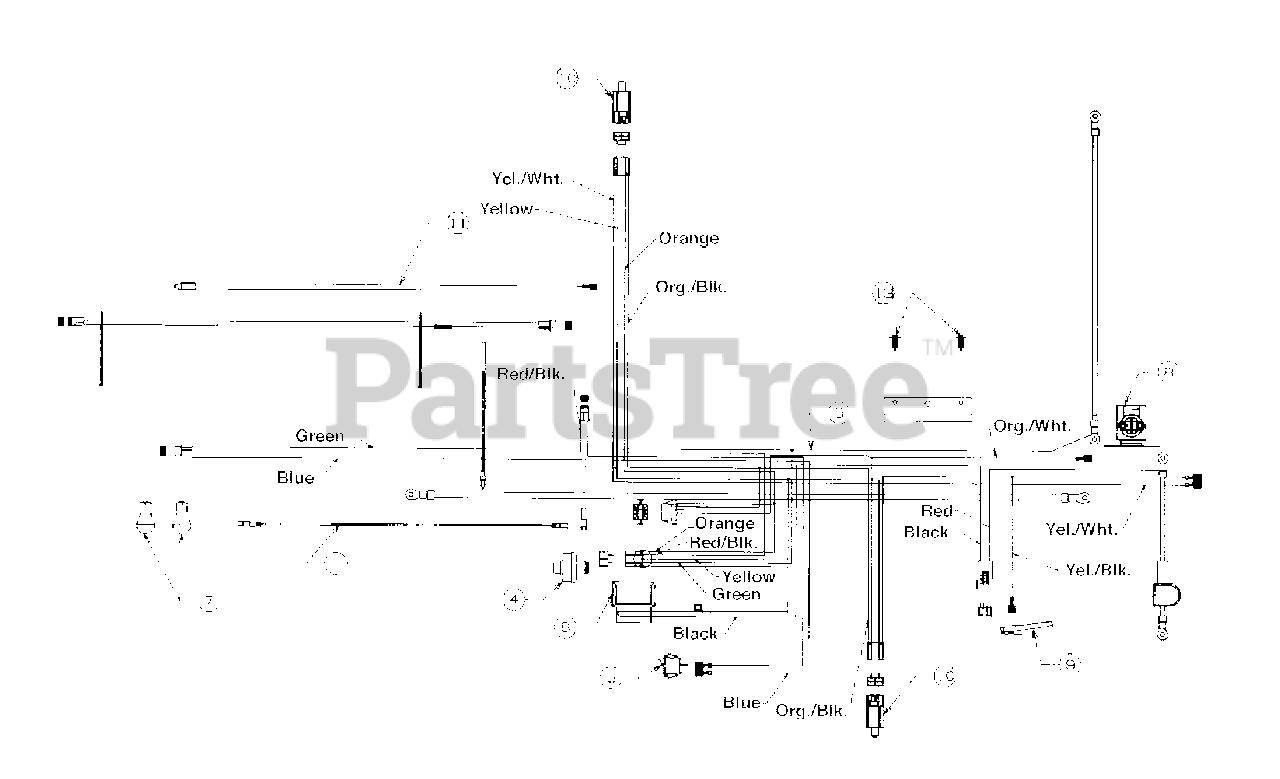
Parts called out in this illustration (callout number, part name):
2	Harness Adapter
3	Wire Harness w/Light Switch & Amp
4	Ignition Switch
5	Light Switch
6	Ammeter
7	Bulb
8	Solenoid
9	Safety Switch
10	Safety Switch
11	Harness Adapter
13	Ratchet
